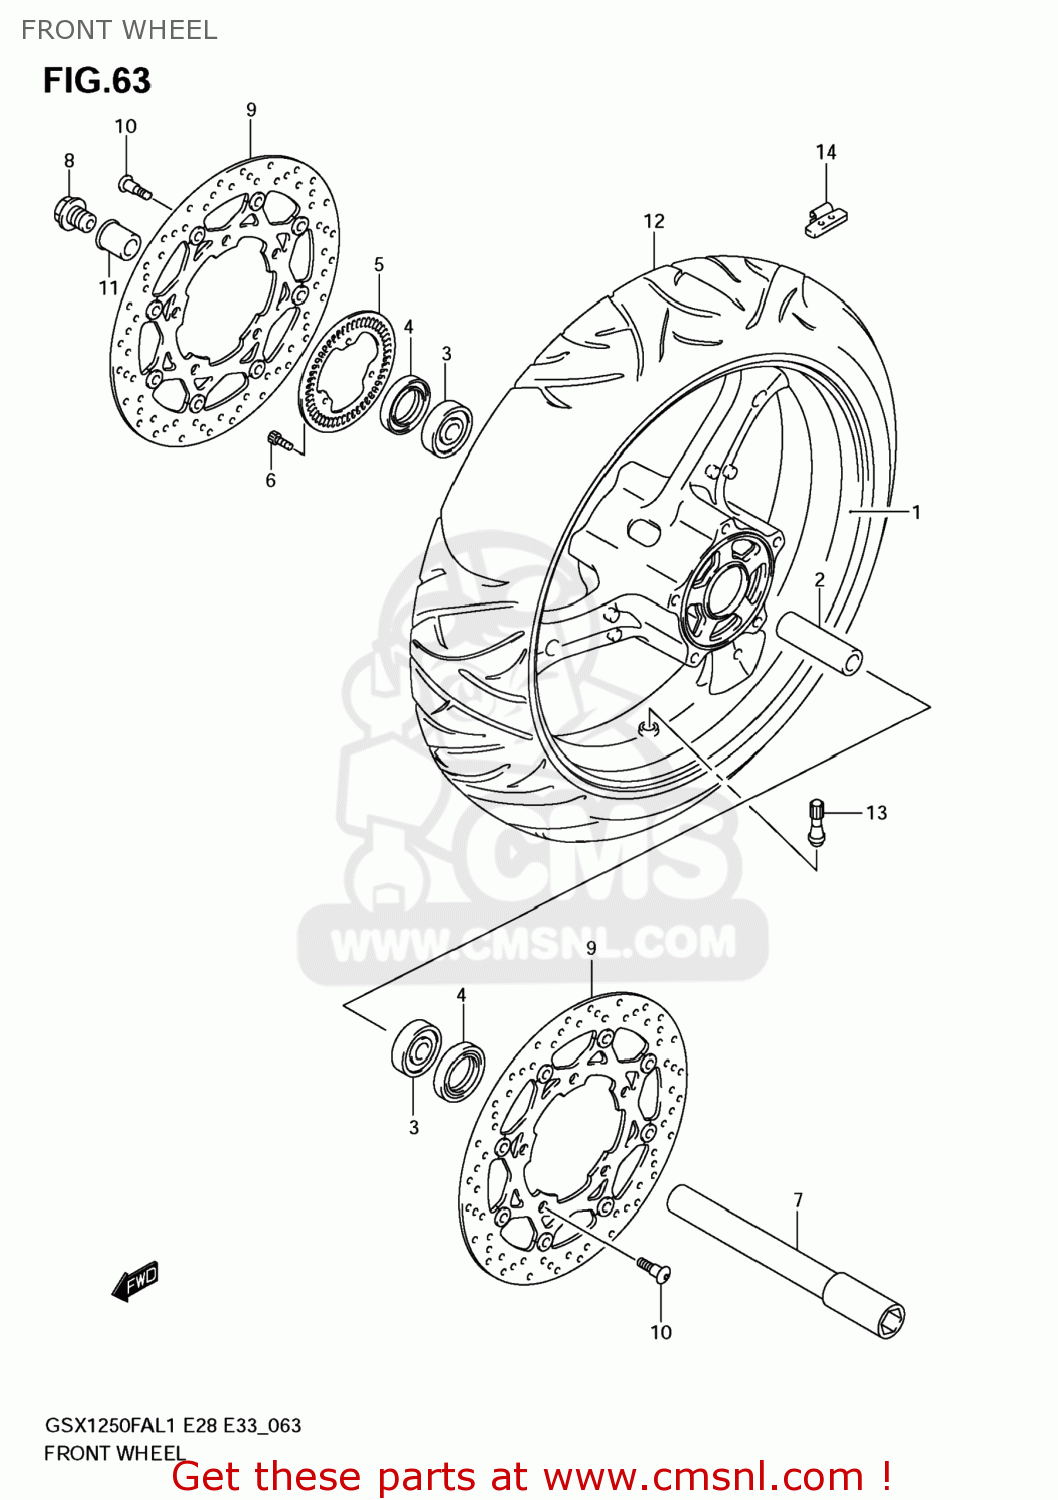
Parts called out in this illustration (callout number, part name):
1	WHEEL,FR(17M/CXMT3.50)
2	SPACER,FR HUB BEARING
3	BEARING(25X52X15)
4	SEAL,OIL(32X52X7)
5	RING,SPEED SENSOR FR(50T)
6	BOLT
7	AXLE,FR
8	BOLT,FR AXLE
9	DISC,FR BRAKE
10	BOLT(8X21)
11	SPACER,FR AXLE,R
12	TIRE,FR
13	VALVE ASSY,WHEEL RIM(TR412)
14	BALANCER,WHEEL(10G)
